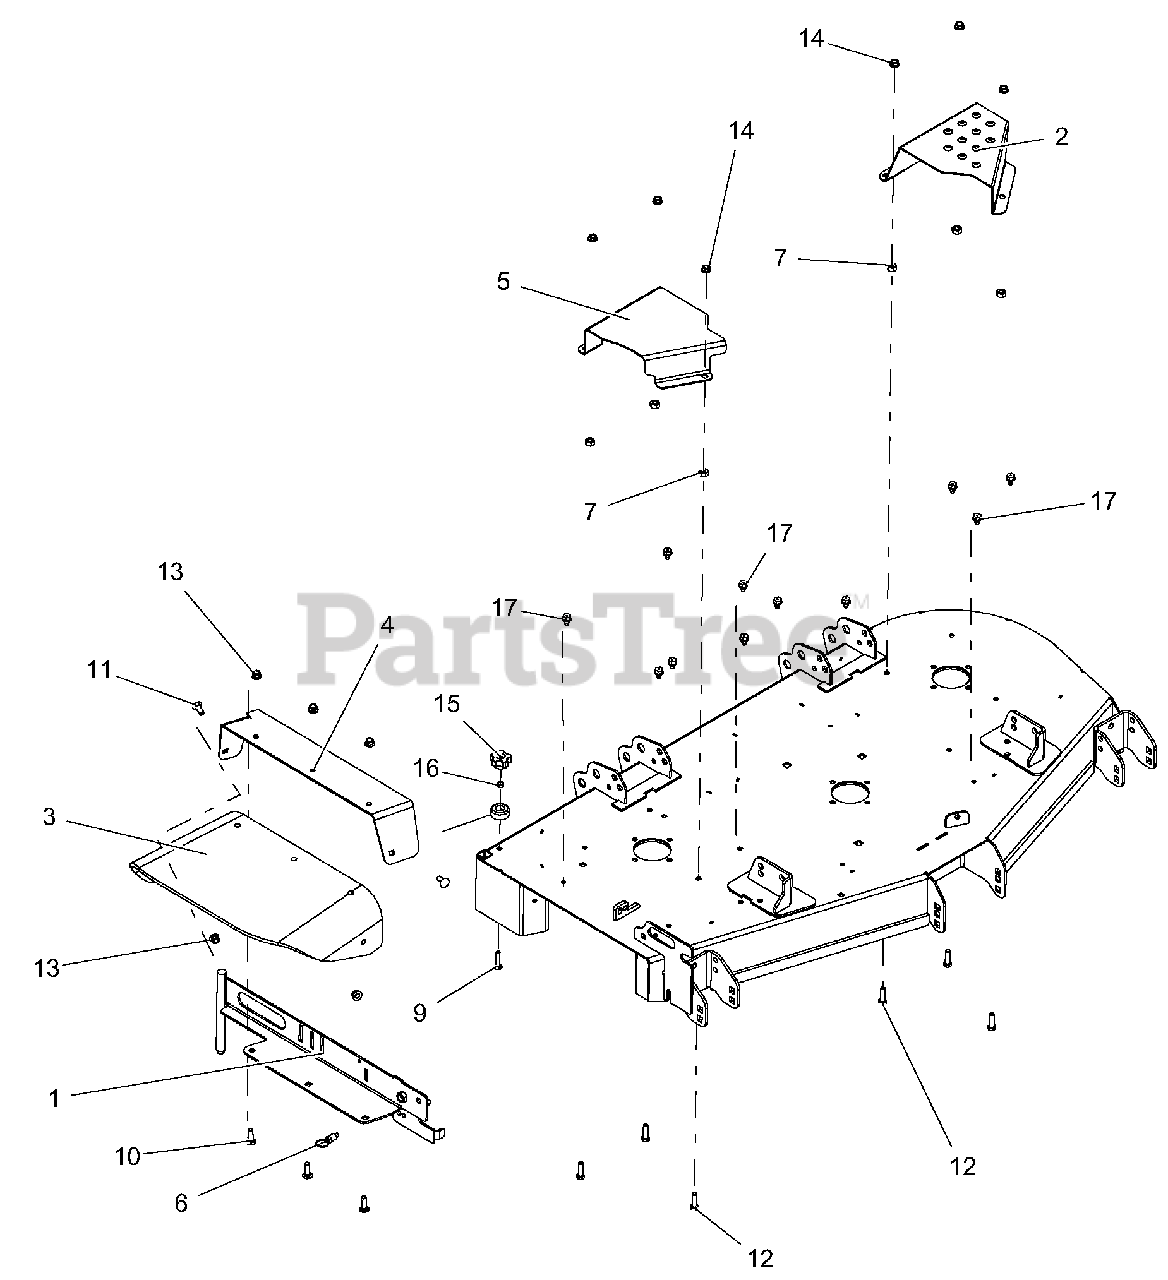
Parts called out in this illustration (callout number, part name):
1	WLDMT, 52"-60" DISCH CHUTE MTG-RED
2	GUARD, 44-52" LH DECK BELT-BLACK
3	CHUTE, RUBBER DISCHARGE
4	KIT, PT DISCH CHUTE SUPT W/SAFETY DECALS-RED
5	GUARD, 48"-52" RH DECK BELT-BLACK
6	PULL PIN,.50-13THDX.310 PLNGR
7	NUT-HEAVY HEX .38-16 YWZC
8	BUMPER, RECESSED 1.50 X .63 W/.31 HOLE
9	BLT-RDHDSQNK .31-18X1.50 G5 YWZC
10	BLT-RDHDSQNK .38-16X1.25 G5 YWZC
11	BLT-RDHDSQNK .38-16X1.00 G5 YWZC
12	BLT-HEX .38-16X1.25 GR5 YWZC
13	NUT-LK-NYL-FLG .38-16 YWZC
14	@NUT-SPNLK-FLG .375-16 YWZC
15	KNOB, CLAMPING
16	NUT-LK-CTR .31-18 YWZC
17	SCR-TAP .38-16X.50 HWH TR YWZ
